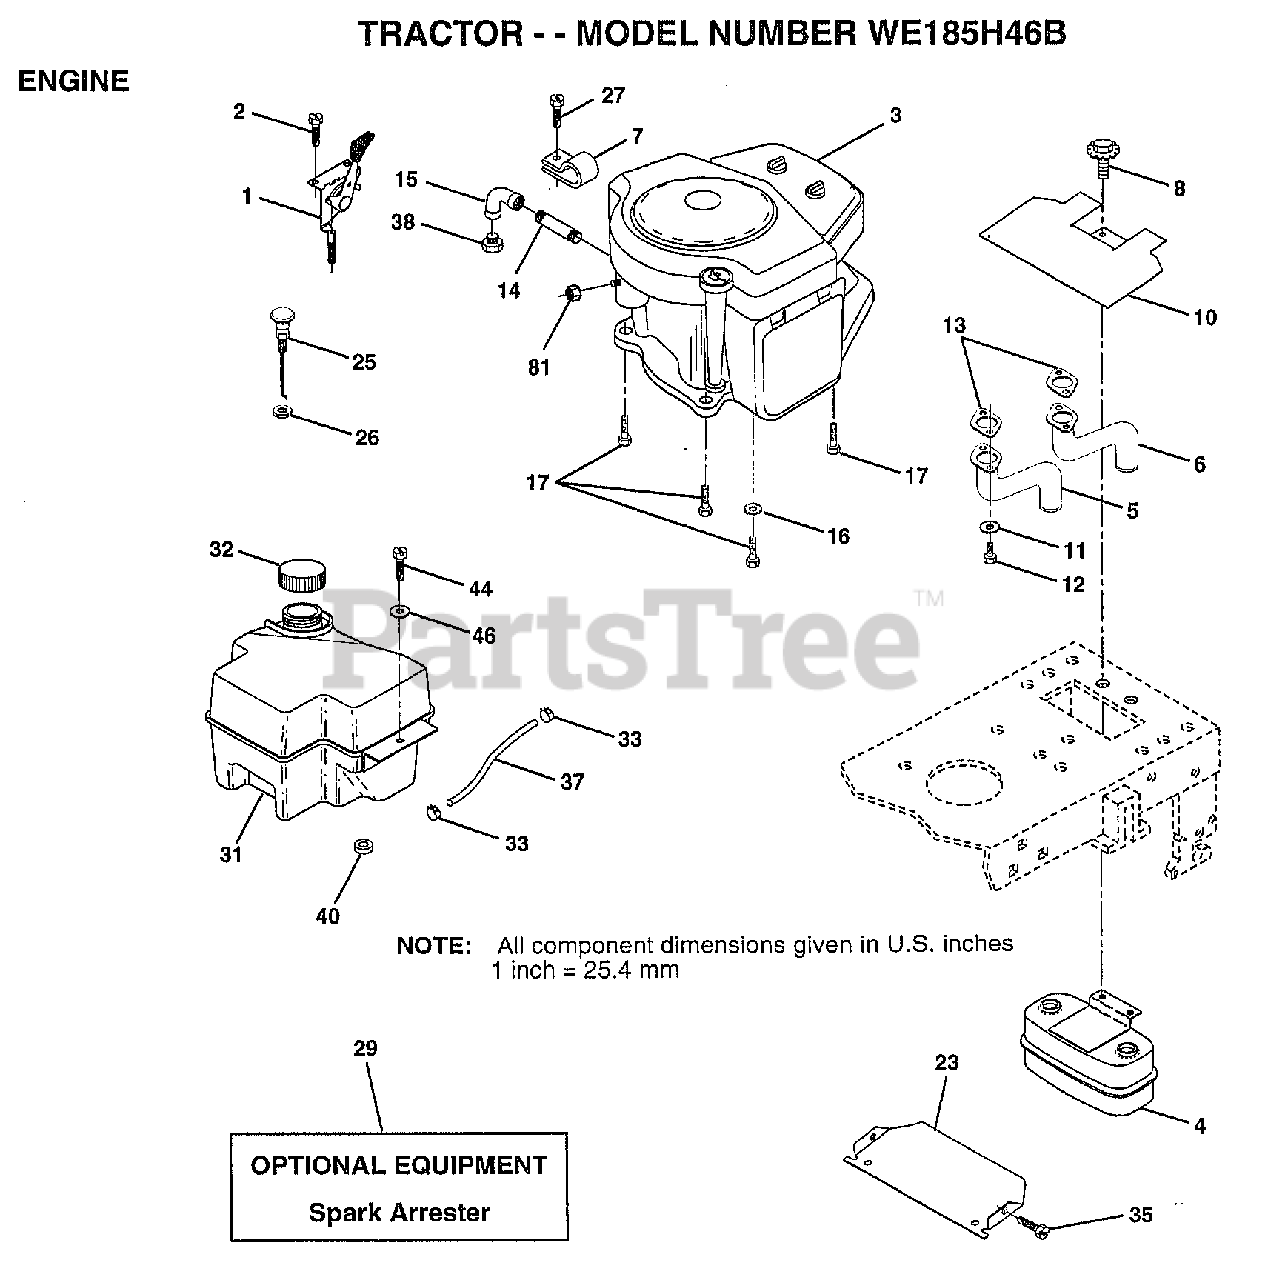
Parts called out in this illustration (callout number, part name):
1	CONTROL THRT 35.5
2	SCREW LT
4	MUFFLER.TW.LOTONE
5	EXHAUST.B&S.18.LH
6	EXHAUST.B&S.18.RH
7	CLAMP.TUBE.DBL.EN
8	BOLT.5/16-18.UNC
10	SHIELD.HEAT.
11	LOCKWASHER
13	GASKET MUFFLER
14	PIPE NIPPLE LT
15	ELBOW
16	LOCKWASHER
17	SCREW LT
23	SHIELD.BRN/DBR.GD
25	CONTROL.CHOKE.37
26	"NUT,KEPS 3/8-24IM"
27	"SCREW-TT,10-32 FL"
31	TANK.FUEL.FRONT.
32	CAP ASM FUEL
33	HOSE CLAMP
35	SCREW
37	LINE FUEL
44	SCREW HEX CRT
46	WASHER
81	NUT
